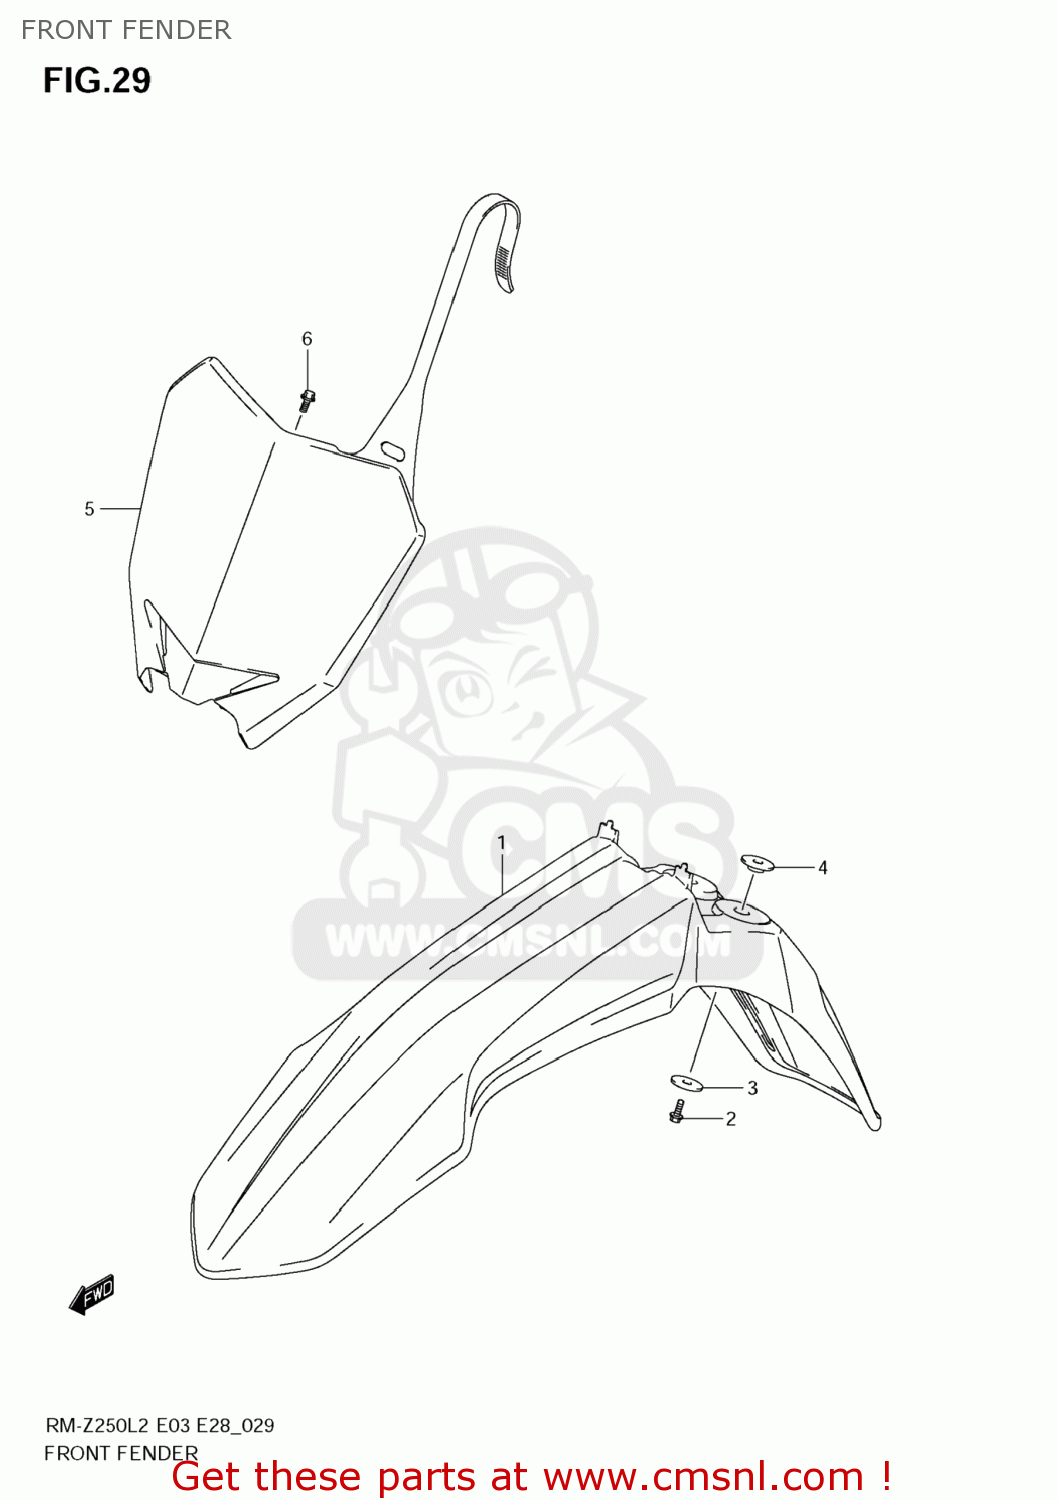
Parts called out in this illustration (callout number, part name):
1	FENDER,FR
2	BOLT
3	WASHER,FUEL TANK FR
4	WASHER
5	PLATE.NUMBER FR
6	BOLT(6X12)
